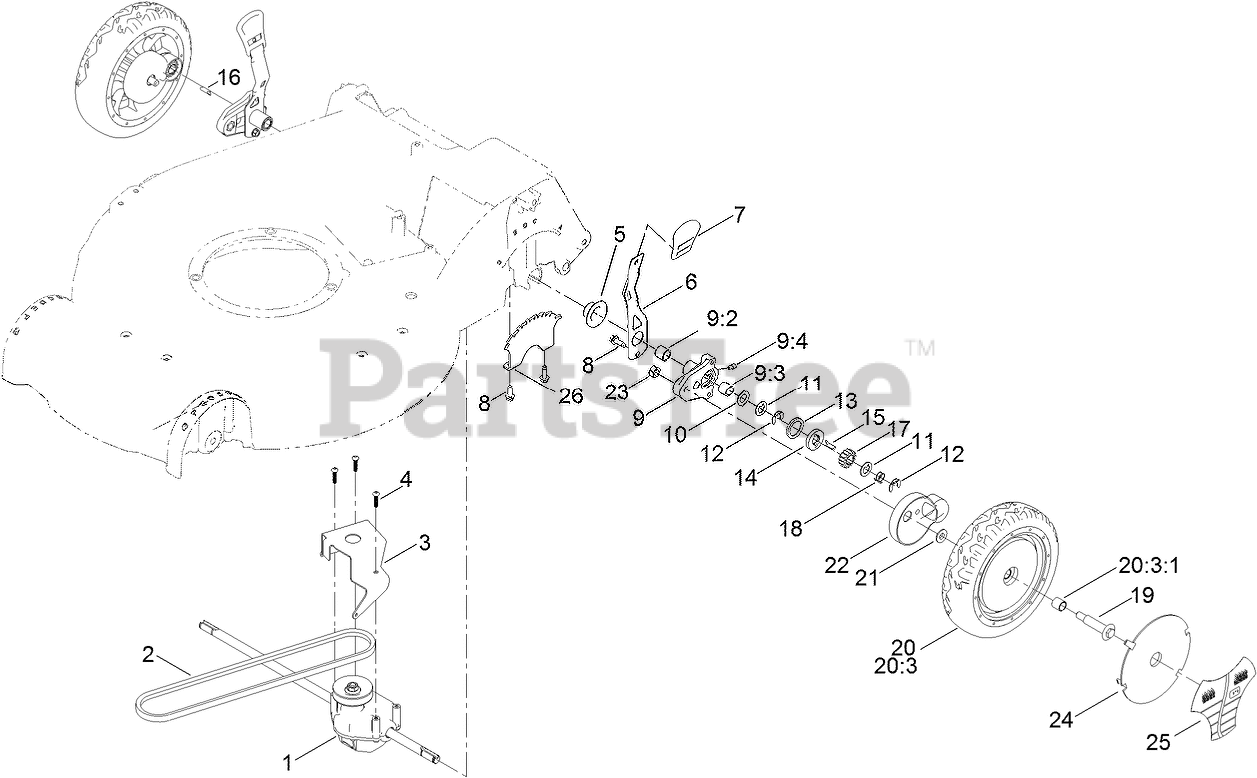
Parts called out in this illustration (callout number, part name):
1	TRANSMISSION ASM
2	BELT-V
3	BRACKET-TRANSMISSION
4	SCREW-PLASTITE
5	CAP-END
6	ARM-SPRING
7	KNOB-HOC
8	SCREW-HWHTF
9	PIVOT ARM ASM
9:2	BUSHING
9:3	BUSHING
9:4	FITTING-GREASE
10	WASHER-ARM, PIVOT
11	WASHER-THRUST, KEYED
12	RING-RETAINING,CLIP
13	RING-FRICTION
14	WASHER-CLUTCH
15	KEY-ROCKING, LH
16	KEY-ROCKING, RH
17	GEAR-PINION
18	SPRING-COMPRESSION
19	BOLT-SHOULDER
20	8 INCH WHEEL AND GEAR ASM
20:3	Loose Parts Package
20:3:1	BUSHING
21	SPACER-COVER, WHEEL
22	COVER-WHEEL
23	LOCKNUT
24	COVER-WHEEL
25	LABEL-WHEEL, SMART
26	PLATE-HOC
